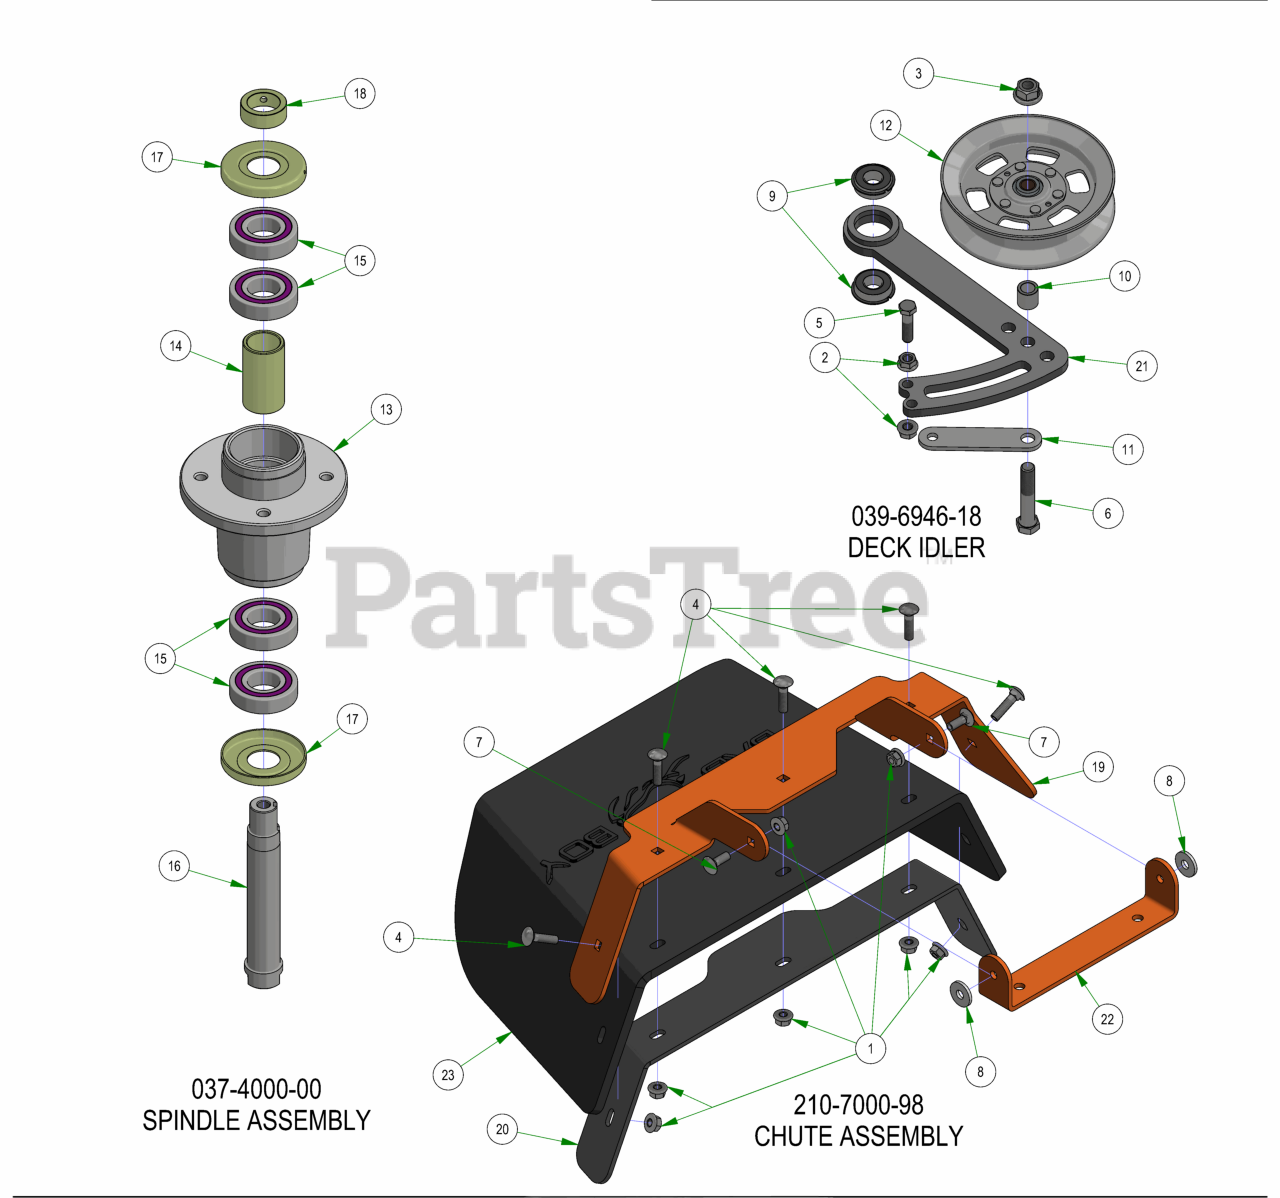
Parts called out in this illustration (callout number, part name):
1	5/16-18 NYLON INSERT FLANGE LOCKNUT ZINC
2	3/8-16 HEX SERRATED FLANGE NUT HARD/ZINC
3	1/2-13 NYLON INSERT FLANGE LOCKNUT ZINC
4	5/16-18 X 1-1/4 CARRIAGE BOLT ZINC
5	3/8-16 X 1-1/2 HEX CAP SCREW (GR.5) ZINC
6	1/2-13 X 2-3/4 HEX CAP SCREW (GR.5) ZINC
7	5/16-18 X 7/8 CARRIAGE BOLT ZINC
8	.360 ID X .983 OD X .120 THICK FLAT WASHER NYLON
9	Ball Bearing w/Retainer, 99502H-NR, .625 Bore x 1.375 OD x .4375 Width
10	.51 ID X .75 OD X .75 LGTH SOLID SPACER ZINC
11	Belt Tensioner Retainer Plate
12	5" Idler Pully
13	4000 Series Spindle Housing
14	4000 Series Spindle Spacer
15	Bearing - 6206
16	Spindle Shaft
17	Spindle Dust Cap
18	Locking Collar w/ 1/4"-20 Set Screw
19	2019 Upper Chute Bracket
20	2019 Lower Chute Bracket
21	2019 Deck Belt Tensioner
22	2019 Chute Hanger
23	2019 Belted Chute with Logo
